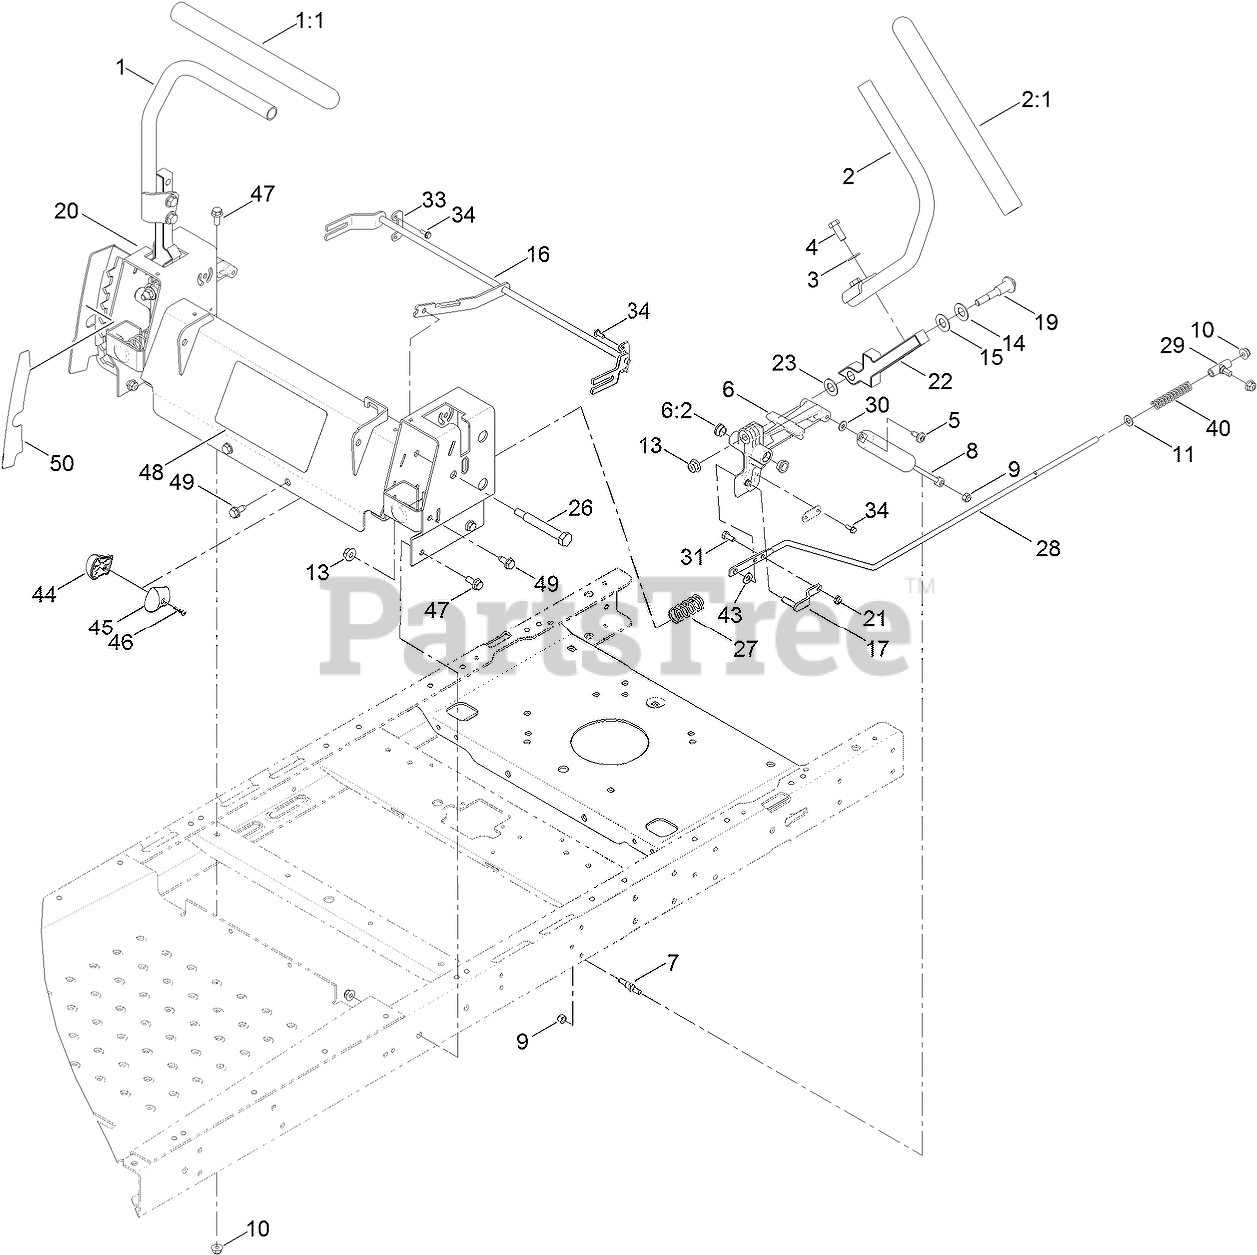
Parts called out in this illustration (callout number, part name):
1	HANDLE-CONTROL, RH
2	HANDLE-CONTROL, LH
3	WASHER-FLAT
4	SCREW-HH
5	SCREW-SHOULDER
6	ACTUATOR ARM ASM
6:2	BUSHING-FLANGE
7	STUD-DAMPER
8	Damper-Control, Motion
9	NUT-LOCK, NI
10	NUT-HF, NI
11	WASHER-PLAIN
13	NUT-HF, NI
14	WASHER-BELLEVILLE
15	WASHER
16	SPEED CONTROL ASM
17	PIN-ROD, HYDRO
19	BOLT-PIVOT
20	CONTROL BOX ASM
21	NUT-LOCK, NI
22	LEVER-CONTROL
23	WASHER-NYLON
26	BOLT-PIVOT
27	SPRING-RETURN
28	ROD-HYDRO
29	MOUNT-ROD, HYDRO
30	WASHER
31	SCREW-HH
33	RETAINER
34	SCREW-TAPTITE
40	SPRING-RETURN, NEUTRAL
43	SPACER-NYLON
44	KNOB-RH
45	KNOB-LH
46	SCREW-PPH
47	SCREW-HHF
48	DECAL-CONTROL, SPEED
49	SCREW-HWHTF
50	DECAL-HOC, CE
